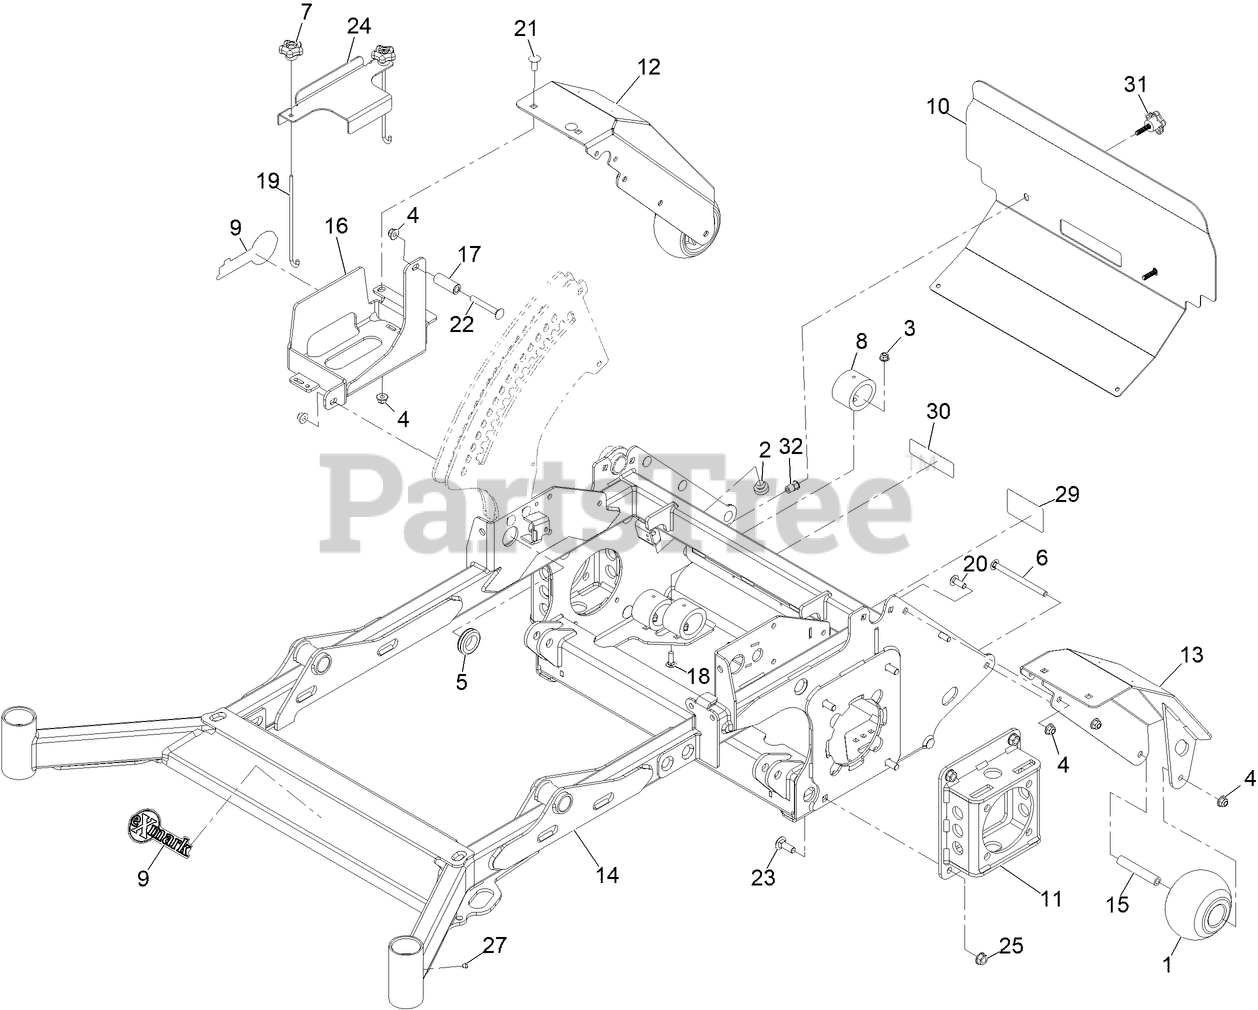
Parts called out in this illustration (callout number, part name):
1	ROLLER-SCALP, ANTI
2	BUMPER-RUBBER
3	NUT-HF, NI
4	NUT-HF, NI
5	GROMMET
6	BOLT-CARR
7	KNOB-HANDLE
8	BUMPER-ISOLATOR
9	DECAL-EXMARK LOGO
10	GUARD-REAR FOOT
11	WLD-MTR MOUNT 60
12	Fender- Wheel RH [red]
13	Fender- Wheel LH [red]
14	Mainframe ASM - 60
15	SPACER- ROLLER
16	Tray-Battery
17	SPACER- ROLLER
18	BOLT-CARR
19	BOLT-HOLDDOWN
20	SCREW-CARR
21	SCREW-CARR
22	SCREW-CARR
23	BOLT-CARR
24	BRACKET-BATTERY HOLD DOWN
29	DECAL-DRIVE RELEASE
30	DECAL-COVER, MISSING
32	NUT-CLINCH
